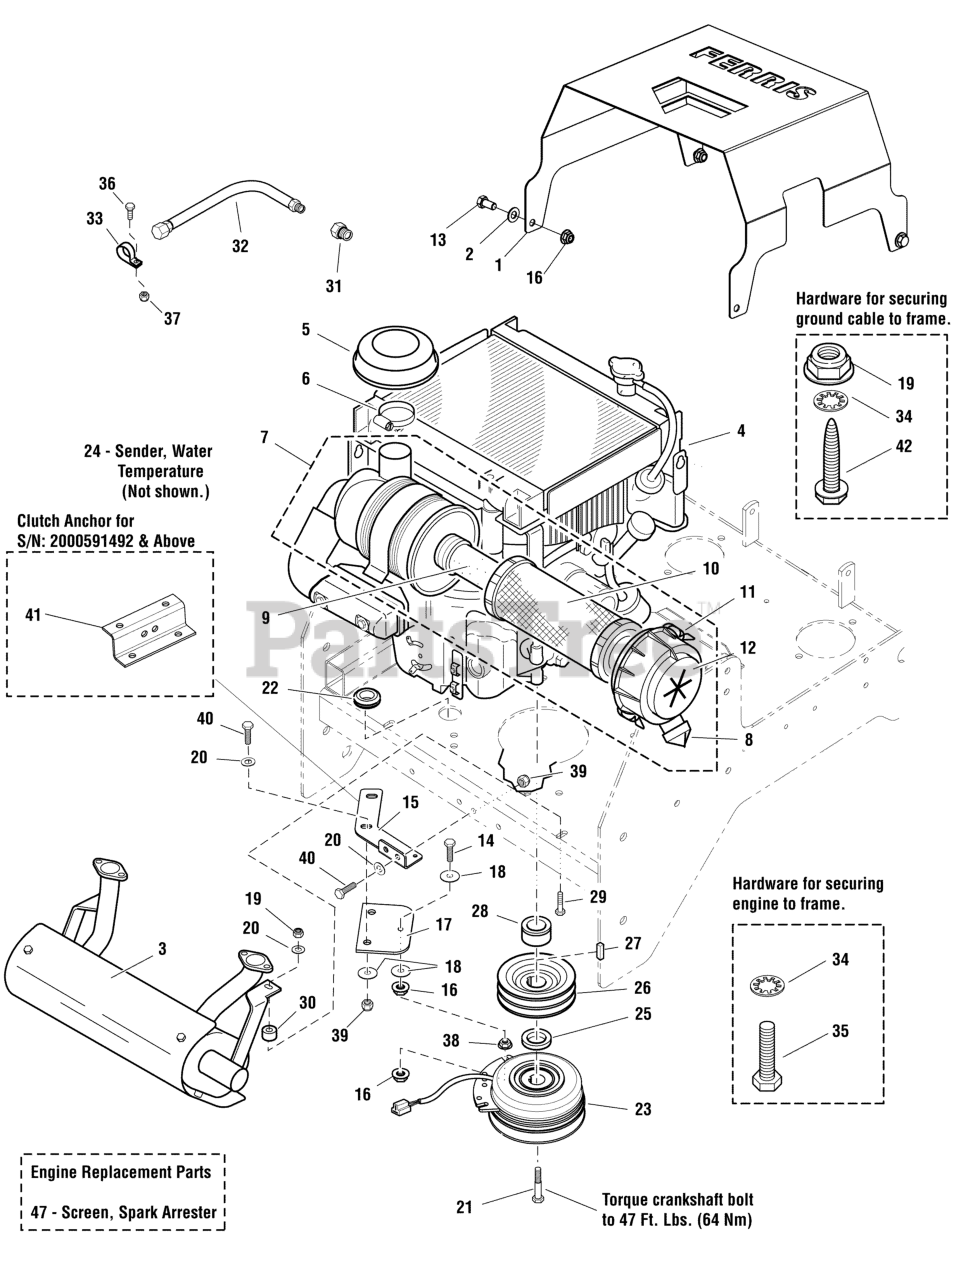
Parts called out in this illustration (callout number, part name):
1	GUARD, RADIATOR SCREEN PROTECTOR - RED
2	WASHER, 3/8 SAE
3	MUFFLER, KAWASAKI LC
4	ENGINE, 26 HP KAWASAKI, LC
5	RAIN CAP
7	AIR FILTER ASSEMBLY, COMPLETE
8	RUBBER, Dust Valve
9	AIR FILTER, SECONDARY
10	AIR FILTER, PRIMARY
11	CLAMP, CAP
12	CAP, FILTER CASE
13	BOLT, 3/8-16 X 1" GD5 CZ
14	BOLT, 5/16-18 X 2-1/4 TFL, GD5 YZ
15	PLATE, CLUTCH ANCHOR
16	NUT, 3/8-16 HEX NYLOCK FLANGE
17	CLUTCH ANCHOR PAD
18	WASHER, .34 X 1.25 X 10 GA
19	NUT, 5/16-18 HEX NYLOCK FLANGE
20	WASHER, 5/16" SAE
21	BOLT, CRANKSHAFT, M10 X 65MM
22	GROMMET, 7/8
23	* CLUTCH, 5218-134, WARNER
25	SPACER, 1.13 X 1.75 X .375
26	PULLEY, CRANKSHAFT (DOUBLE A)
27	KEY, 1/4 SQ X 1
28	SPACER, 1.13 X 1.75 X 1.03
29	BOLT, 5/16-18 X 1-3/4" GD5
30	SPACER, .39 X 1.00 X .80
31	ADAPTER, OIL DRAIN
32	HOSE, OIL DRAIN
33	CLAMP, VINYL
34	WASHER, 5/16" INT. TOOTH LOCK
35	BOLT, M8-1.25 X 25MM GD8.8
36	BOLT, 1/4-20 X 1" GD5 CZ
37	NUT, 1/4-20 HEX NYLOCK FLANGE
38	NUT, 5/16-18 HEX SERRATED FLANGE (LARGE)
39	NUT 5/16-18 HEX NYLON LOCK
40	BOLT, 5/16-18 X 1" GD5 YZ
41	ANCHOR, CLUTCH - BLK
42	BOLT, 5/16-18 X 1" , SELF-TAPPING
